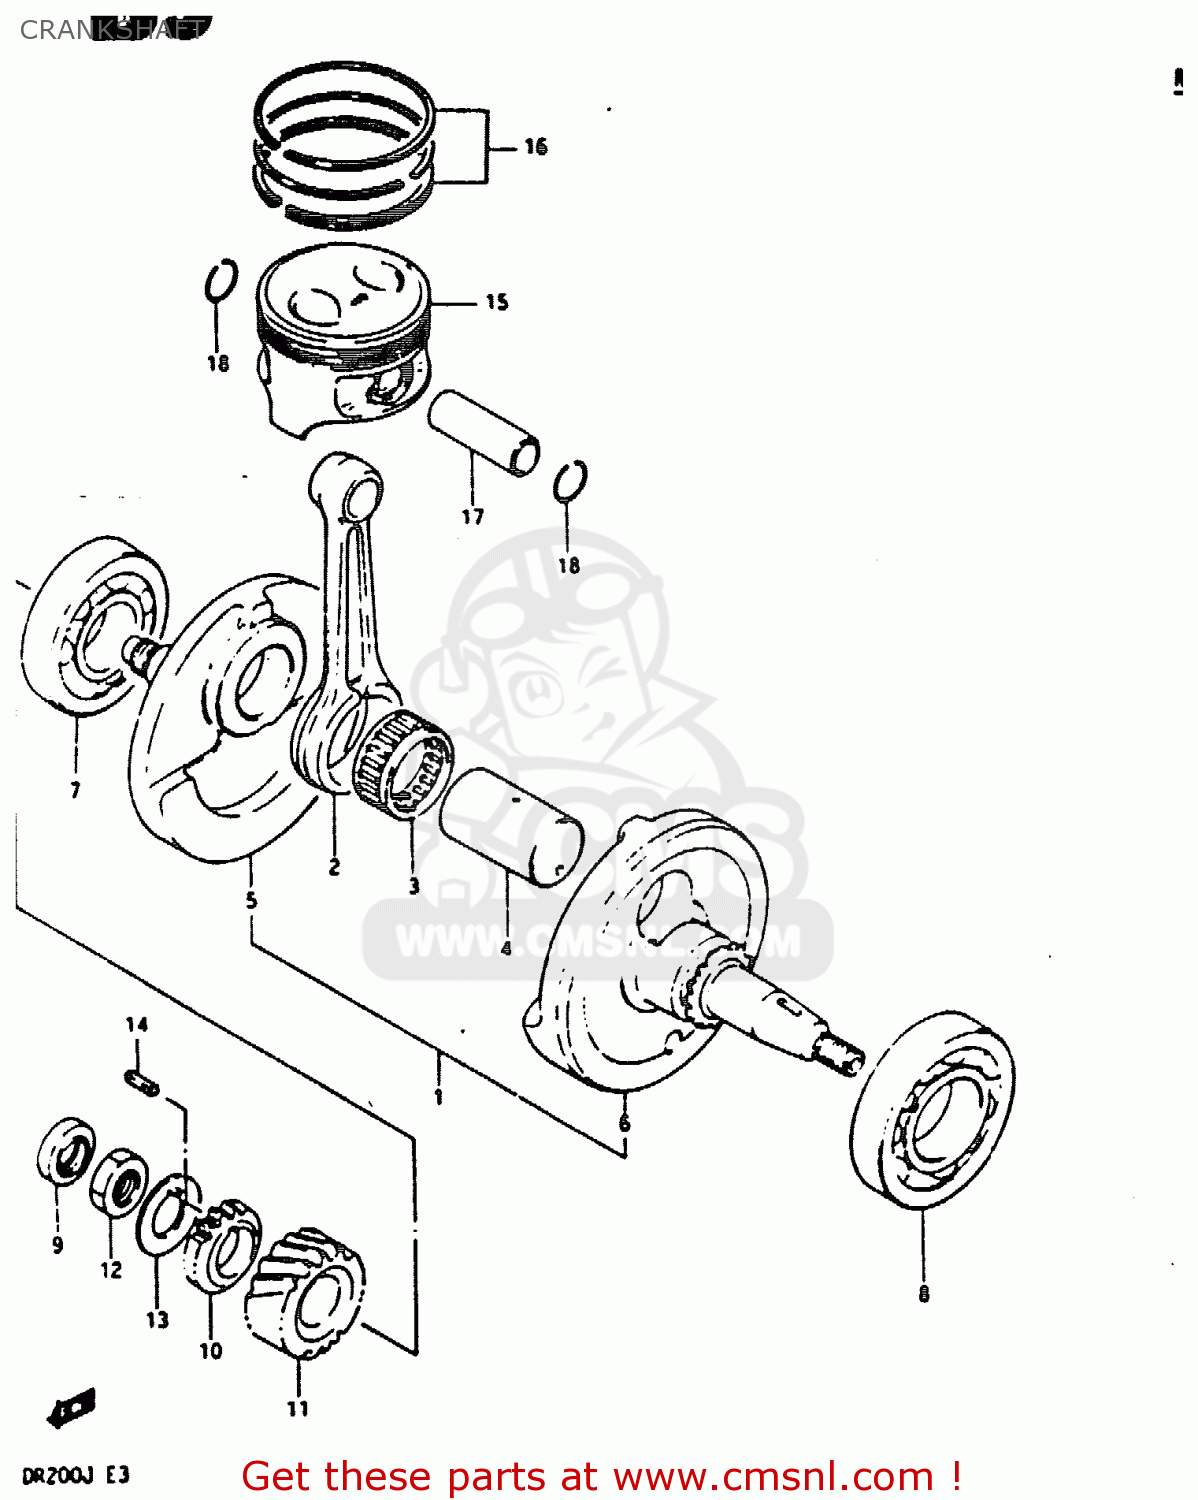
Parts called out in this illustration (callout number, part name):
1	CRANKSHAFT ASSEMBLY
2	CONNECTING ROD
3	BEARING(31X38X18)
4	PIN,CRANK
5	CRANKSHAFT,R
6	CRANKSHAFT,LEFT
7	BEARING(28X68X18)
8	BEARING
9	OIL SEAL
10	GEAR,OIL PUMP DRIVE(NT:15)
11	GEAR,PRIMARY DRIVE (NT:
12	NUT
13	WASHER
14	KEY
15	PISTON
16	RING SET,PISTON
17	PIN,PISTON
18	CIRCLIP
